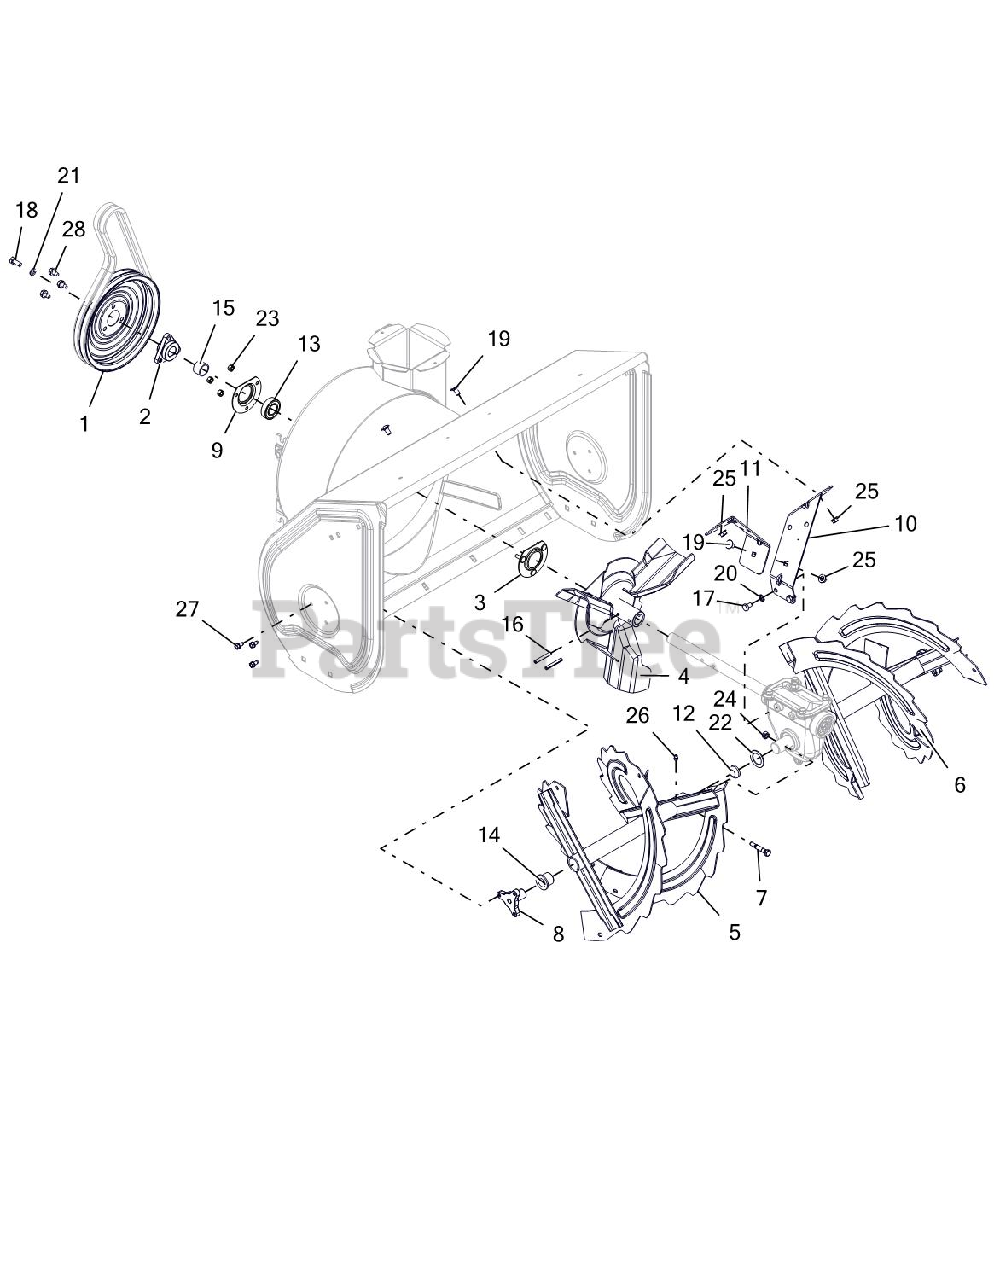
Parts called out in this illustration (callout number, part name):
1	PULLEY, SPIN FORM DUAL GROOVE
2	PULLEY HUB, D-BORE .87 DELUXE
3	BEARING FLANGE
4	IMPELLER, 3 BLADE-14"
5	RAKE, RH W/ZERK - 30"
6	RAKE, LH W/ZERK - 30"
7	SHEAR BOLT SERVICE ASSEMBLY
8	SUPPORT, RAKE BUSHING
9	BEARING FLANGE
10	BRACKET, GEARCASE SUPPORT - LH
11	BRACKET, GEARCASE SUPPORT - RH
12	PLUG, RAKE TUBE
13	BRG-BALL .876 X 1.750 X .50
14	BSHG-FLG, NY.778 ID X 1.018 OD
15	BSHG,SPCR .895X1.065X.693
16	PIN-ROLL .250X1.75
17	@BLT-HEX .31-18X.50 GR5 YWZC
18	BLT-HEX .31-24X.75 YWZC GR5
19	BLT-RDHDSQSHNK.31-18X.62 YZ-LK
20	@WSHR-LK-EXT.326X.599X.031YWZC
21	WSHR-LK .312X.097 HVY YWZC
22	WSHR-FL-STL 1.010X1.505X.062YZ
23	@NUT-LK-CTR .25-20 YWZC
24	@NUT-LK-CTR .31-18 YWZC
25	@NUT-LK-TOP-FLG .31-18 YWZC
26	ZERK,FITTING .25X.125 DRIVE IN
27	SCR-TAP .25-20X.50 HWH TR YWZ
28	@SCR-TAP .31-18X.50 HWH TR YWZ
